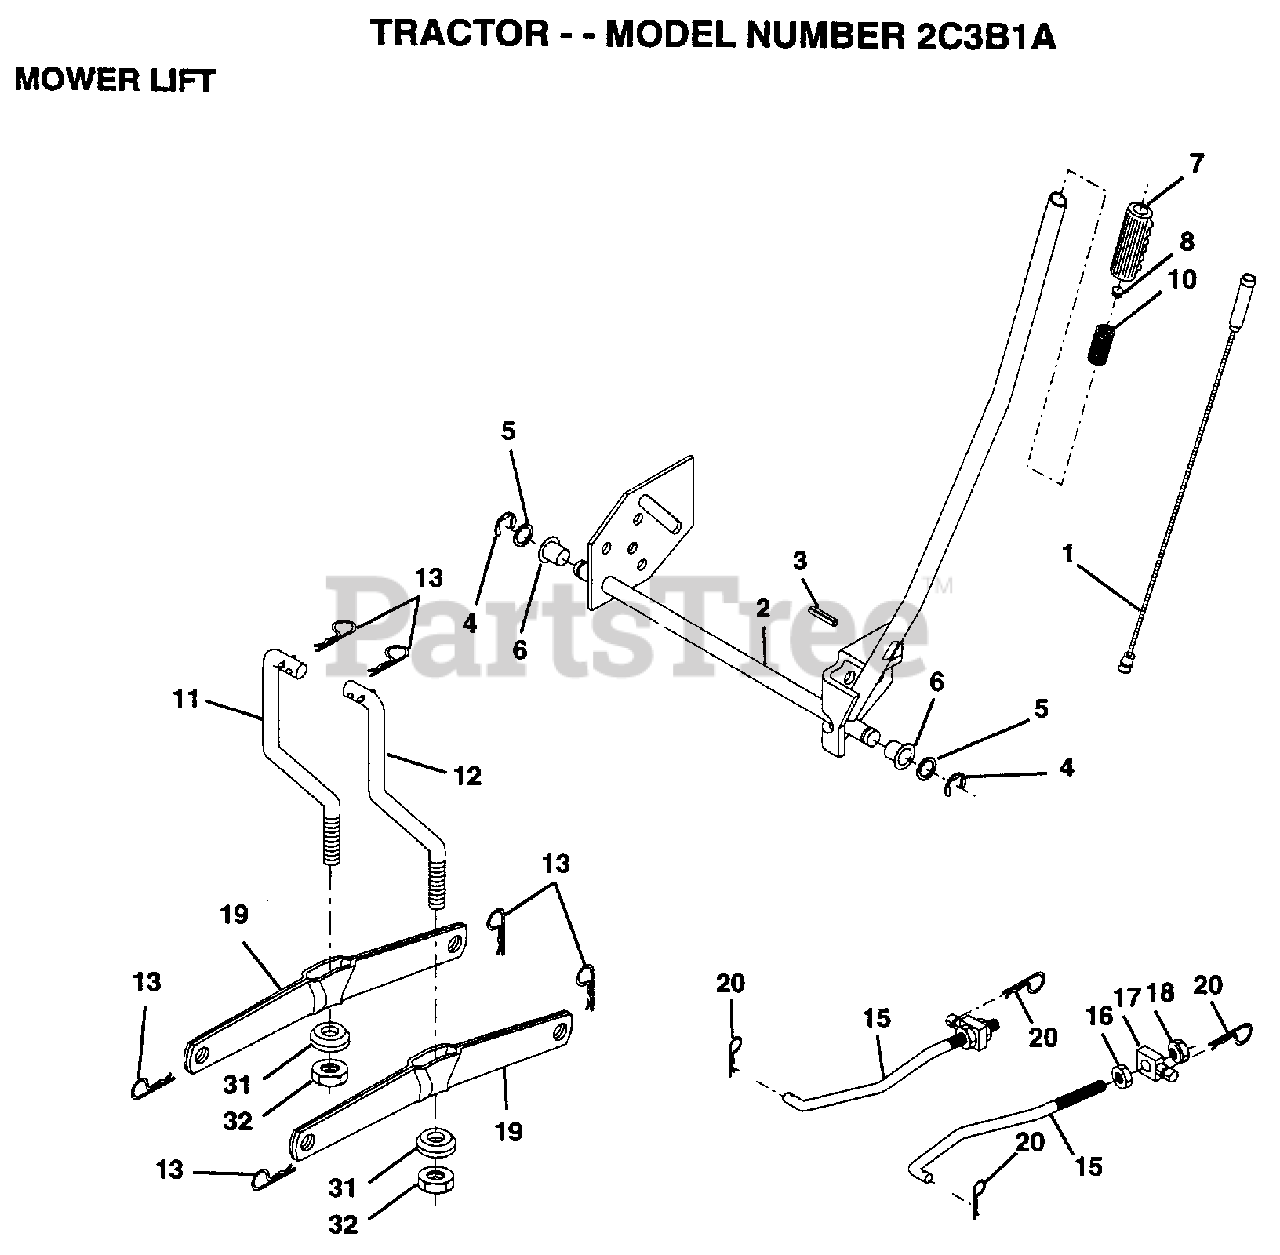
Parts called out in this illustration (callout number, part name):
1	WIRE ASM
3	PIN-GROOVE LT
5	WASHER
6	NYLON BEARING
7	GRIP
8	Button Plunger Black
15	LINK.FRONT
16	NUT
17	TRUNION
18	NUT.LK.W/WSH.1/2.
19	ARM SUSP REAR
20	RETAINER.SPRING
31	BEARING PVT LH
32	NUT.CROWNLOCK.3/8
